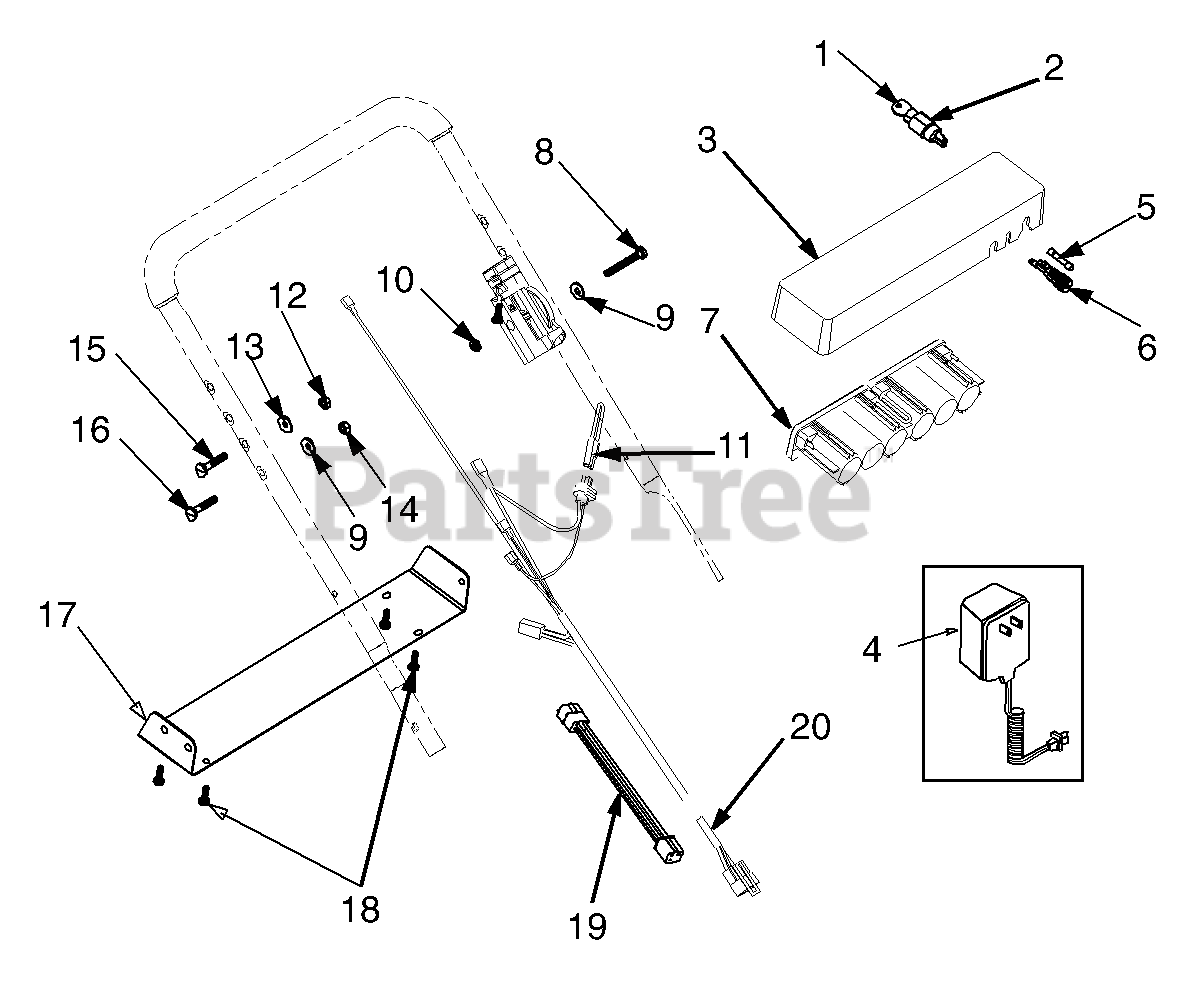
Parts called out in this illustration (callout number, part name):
1	Ignition Key
2	Key Switch
3	Battery Tray
4	Battery Charger
5	Fuse 7.5 Amp
6	Fuse Holder
7	Battery 12V
8	Hex Screw:1/4-20:2.0
9	Bell Washer
10	Special Hex Nut 5/16-18
11	Plug
12	Nut 5/16-18
13	Bell Washer
14	Hex Nut 1/4-20
15	Carriage Bolt
16	Carriage Screw
19	Harness Extension
20	Harness
